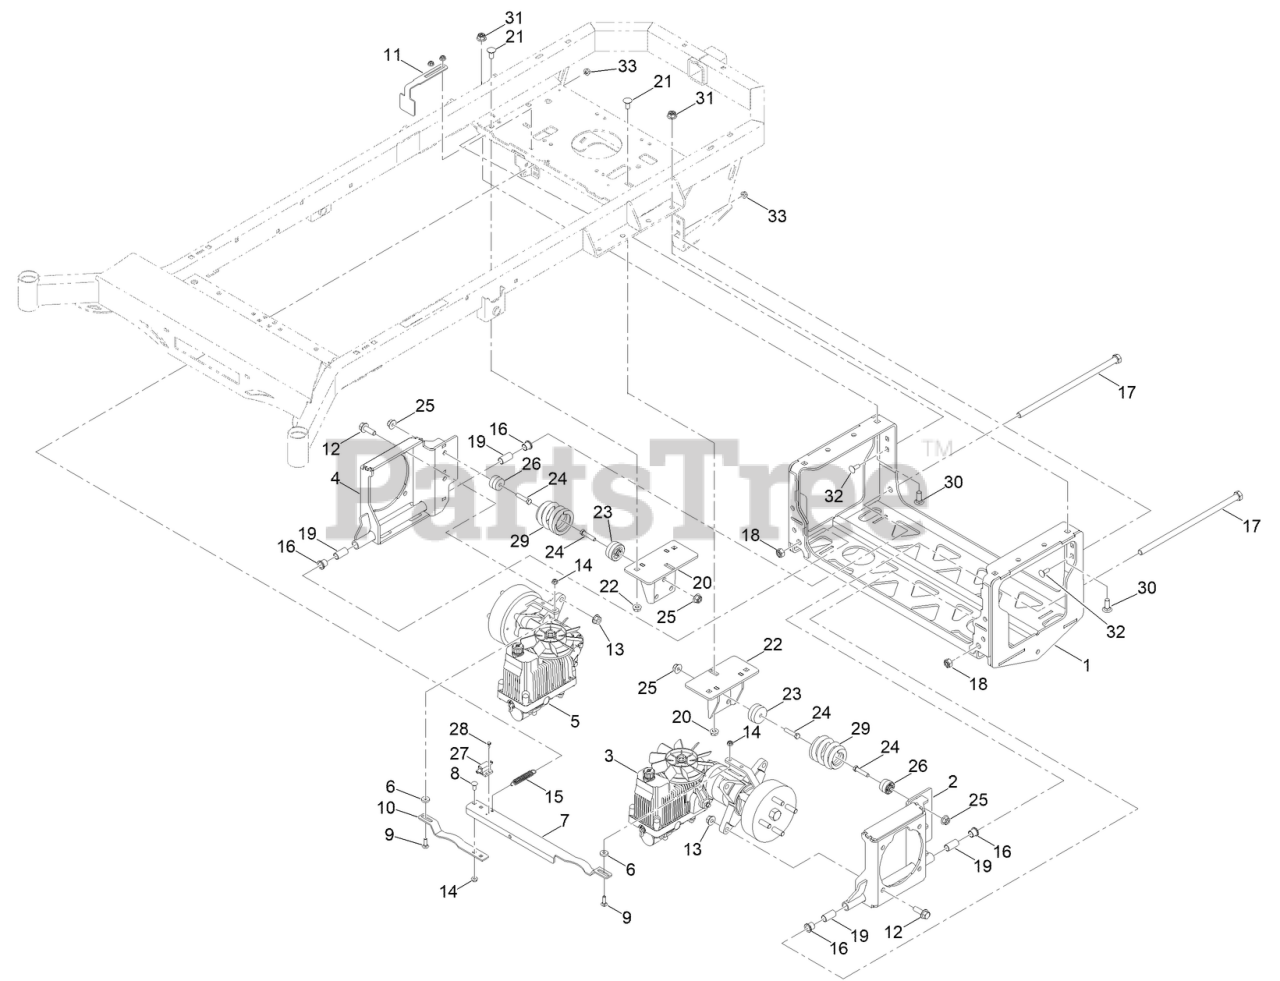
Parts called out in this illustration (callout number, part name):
1	HYDRO FRAME ASM
2	MWR LT RR SUSP ASSY-SRT-PRO HD
3	HTJ12 PARKER LT SIDE HYDROSTATIC TRANSM
4	MWR RT RR SUSP ASSY-SRT-PRO HD PAINTED
5	HTJ12 PARKER RT SIDE HYDROSTATIC TRANSM
6	.312 ID X .875OD X .1875 THK F/W NYL
7	MWR PARK BRAKE BRKT LT PAINT
8	BOLT-CARR
9	BOLT-CARR
10	MWR PARK BRAKE BRKT RT PAINT
11	STAND TRANS BRAKE INTERLOCK BRKT PAINT
12	SCREW-HHF
13	NUT-HHF
14	5/16-18 NYLON INSERT FLANGE L/NUT ZC
15	MWR BRAKE PEDAL RELEASE SPRING
16	BUSHING-FLANGE
17	5/8-11 X 15IN HEX C/S GR 2 ZC 3IN THD L
18	5/8-11 NYLON INSERT FLANGE L/NUT ZINC
19	.625 ID X .750 OD X 1.500IN OI BUSHING
20	MWR SUSP FRAME BRKT ASSY PAINT
21	SCREW-CARR
22	7/16-14 HEX FLANGE NUT W/SERR ZINC
23	SUSP SPRING INSIDE GUIDE
24	3/8-16 X 1-3/4 HEX C/S GR 2 ZINC
25	3/8-16 NYLON INSERT FLANGE L/NUT YZ
26	SUSP SPRING OUTSIDE GUIDE
27	NO PLUNGER LIMIT SWITCH
28	8-32 X 1/2 IND. HWH SLOT TYPE F TCS ZINC
29	SRT RR SUSP SPRING
30	SCREW-CARR
31	1/2-13 HEX FLANGE 2-WAY REV CNTR L/NYZ
32	3/8-16 X 1 CARRIAGE BOLT YZ GR.8
